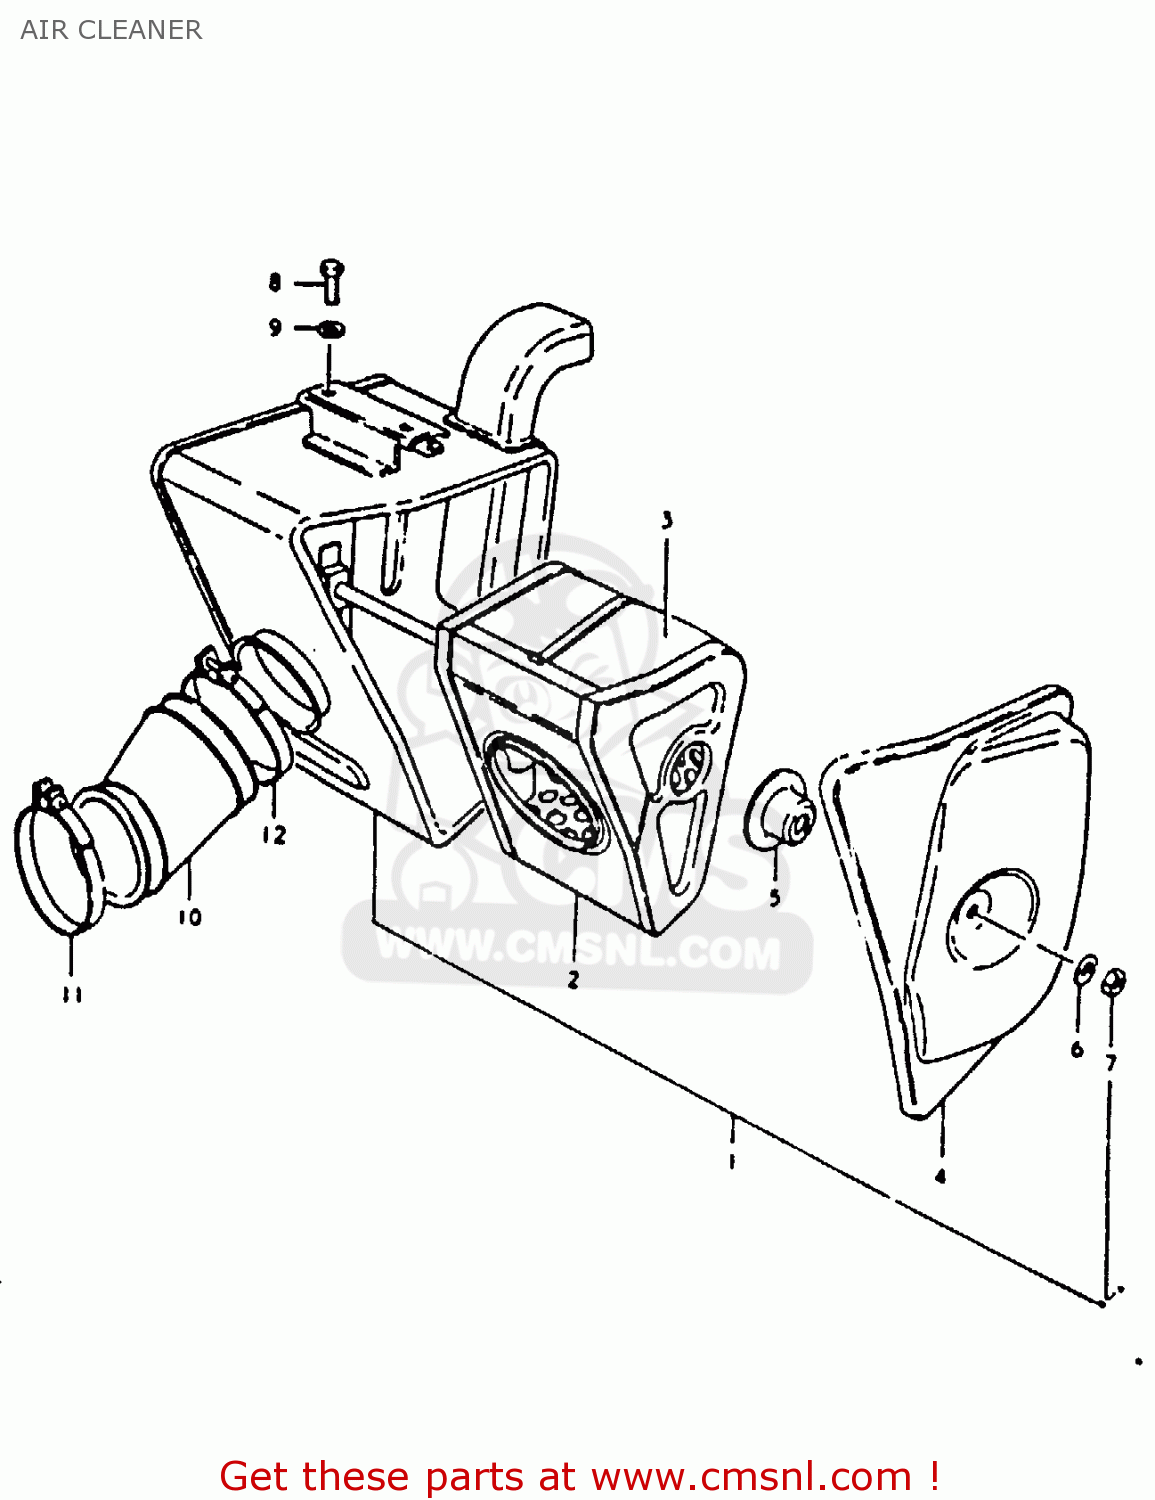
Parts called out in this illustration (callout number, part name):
1	CLEANER ASSEMBLY,AIR
2	FILTER ASSY,AIR CLEANER
3	FILTER
4	CAP
5	SPACER
6	WASHER
7	NUT
8	BOLT
9	WASHER
10	HOSE,CARBURETOR AIR INLET
11	CLAMP
12	CLAMP
